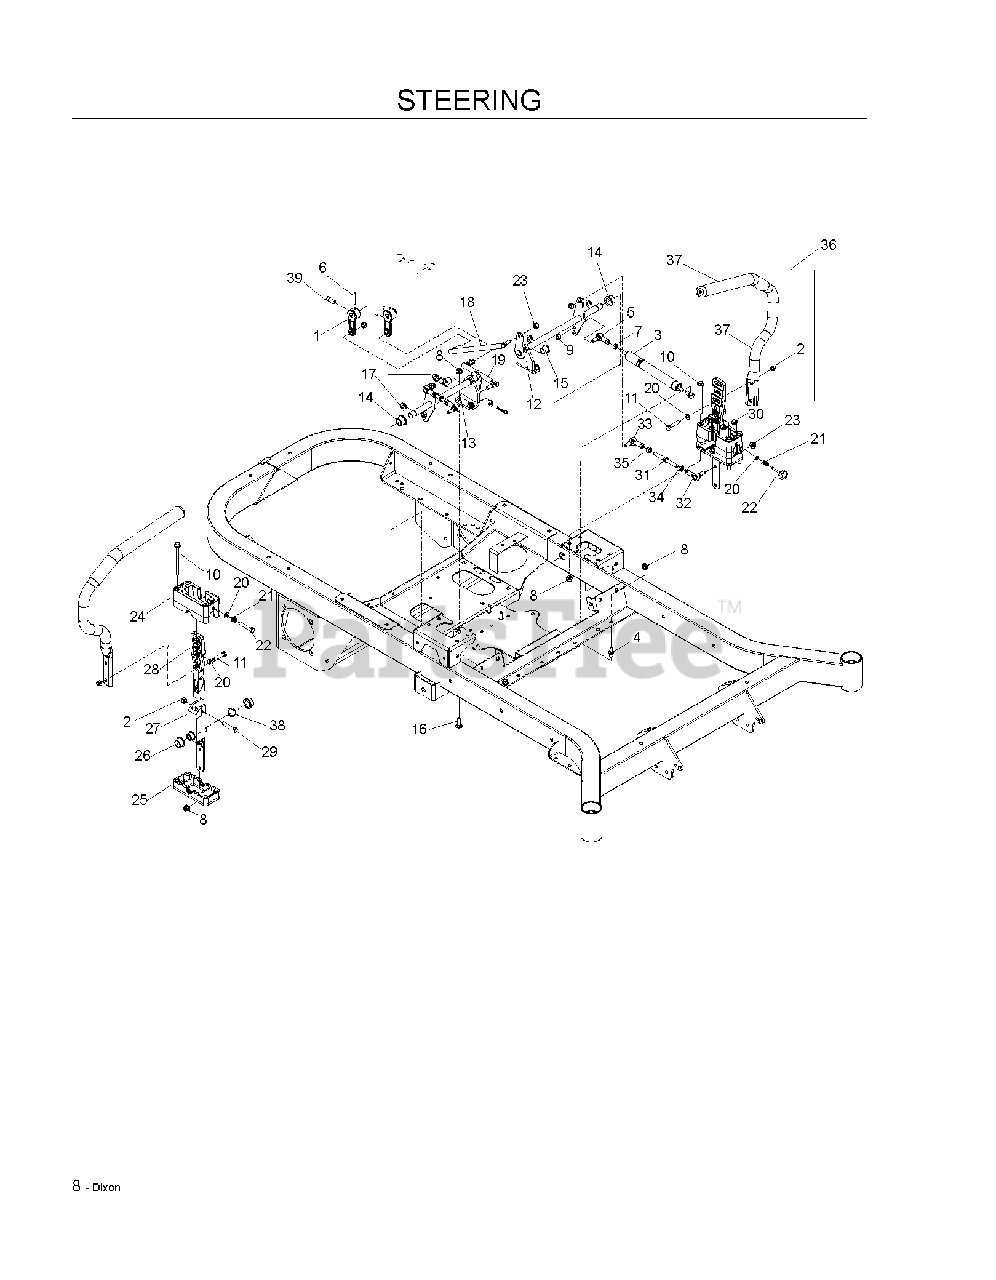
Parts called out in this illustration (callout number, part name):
1	ARM, PUMP
2	NUT 5/16 NYLOC
3	DAMPENER W/SPRING
4	STUD.BALL.10MM
5	ROD END
6	PIN, SPIRAL, 5/32 X 1 1/2
7	NUT M8 X 1.25 STD HEX
8	5/16-18 NYLOC FLANGE NUT
9	NUT M8 NYLOC
10	HHFS 5/16-18 X 3 3/4
11	CAPSCREW 5/16 X 1/1/2 HEX HEAD
12	CONTROL WLDMT, LT
13	CONTROL WLDMT, RT
14	BUSHING, FLANGED, 5/8
15	BUSHING, CLIP, 5/8
16	RHSNB 5/16C X 1
17	E-RING 5/8
18	LINK, MOTION, LT
19	LINK, MOTION, RT
20	FLAT WASHER 5/16 SAE
22	HCS 5/16-18X1-3/4 TPBLT
23	NUT 5/16-24 CNTRLK
24	BLOCK, UPPER
25	BLOCK, LOWER
26	BEARING, FLANGE
27	PIVOT SECTION, DR CNTRL
28	MOUNT, DR CNTRL HANDLE
29	HCS 5/16C X 1 3/4
30	NUT 5/16C HEX
31	JACK SCREW
32	SPHERICAL ROD END, LH
33	SPHERICAL ROD END, RH
34	NUT 5/16F LEFTHAND
35	NUT 5/16F
36	LEVER.DRIVE.W/GRIP
37	GRIP - DRIVE LEVER
38	WASHER, .825 X 1.087, WAVE
39	SCREW 5/16C X 5/8 SQ HEAD
